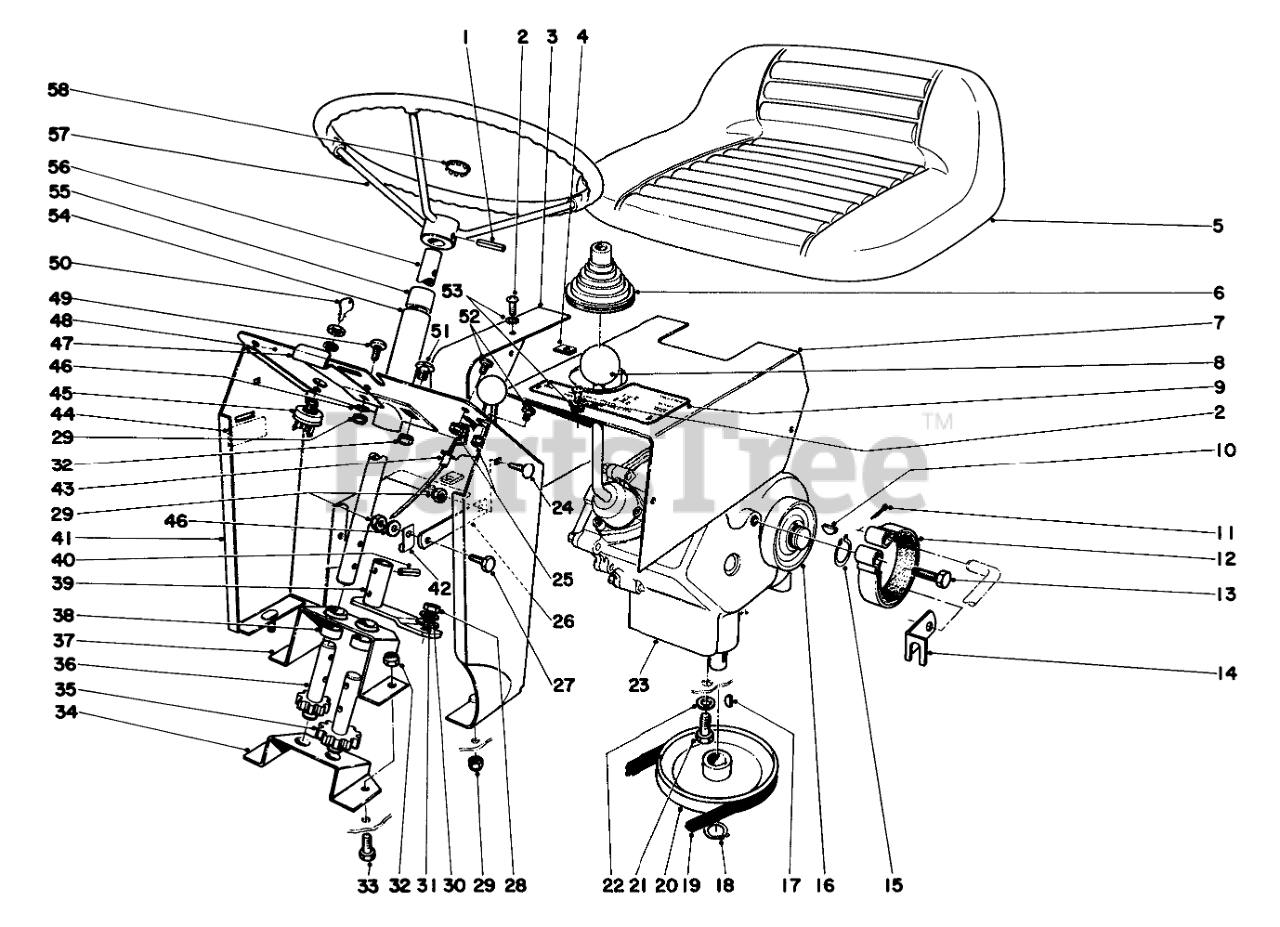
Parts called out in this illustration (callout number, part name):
1	PIN-ROLL
2	10-24 X 3/8 PAN HD SC
3	Chain Guard
4	NUT-CLIP,U
6	Boot Shift Lever
7	Cover Transmission
9	Decal Model 57111
10	KEY-WOODRUFF
11	PIN-COTTER
12	Brake Band
13	He Ha. Screw
14	Retainer Brake Rod
15	Ring-Snap
16	Brake Drum
17	KEY-WOODRUFF
18	RING-SNAP, EXTERNAL
19	TRANS TO ENGINE BELT
20	PULLEY
21	SCREW-HH
22	WASHER-LOCK/SP
23	Transmission
24	SCREW-CARRIAGE
25	NUT-KEPS
26	Hanger Throttle Control
27	SCREW-HH
28	NUT-HEX
29	NUT-LOCK, CONE
30	WASHER-LOCK
31	WASHER-FLAT
32	NUT-LOCK, CONE
33	SCREW-HH
34	Bracket Steering
35	Steering Gear
36	Pinion Gear
37	Support Steering
38	Spacer
39	Steering Arm
40	PIN-ROLL, SLOTTED
41	Rear Hood Support (Recoil)
43	Throttle Control
44	Decal Warning Model 57077
45	STARTER SWITCH
46	WASHER-FLAT
47	Hood Latch
48	Decal Dash Model 57043
49	SCREW-CARRIAGE
50	Key
51	Round Head Screw
52	SCREW-PPH
53	WASHER-LOCK, EXT
54	Steering Tube Assy.
55	BUSHING
56	Shaft Steering
57	Steering Wheel
